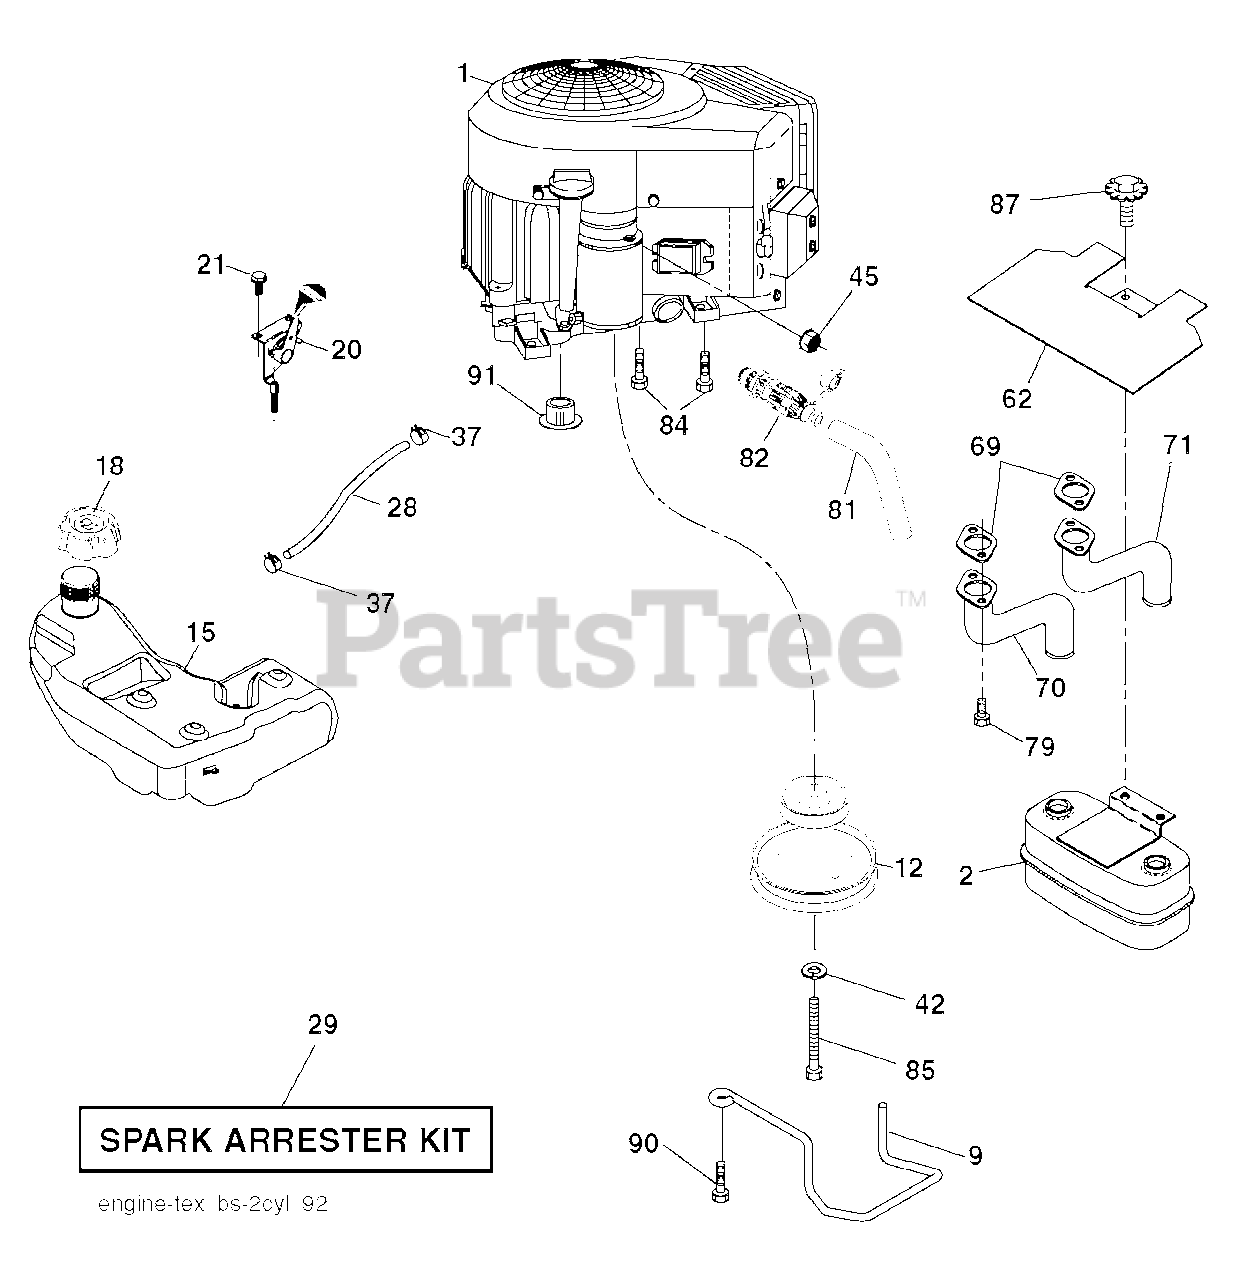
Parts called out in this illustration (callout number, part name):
2	MUFFLER.TWIN.CYL.LOW.TONE
9	KEEPER.BELT.ENGINE.4.2
12	PULLEY ENGINE
15	TANK.FUEL.4GAL
18	CAP.ASM.FUEL.TANK.3"BLACK
20	CONTROL.TH/CK.COBRA.B&S.TWN.
21	SCREW.#10 X 0.750.BOS THREAD
28	LINE.FUEL.20
29	ARRESTER SPARK (OPTIONAL)
37	HOSE CLAMP
42	LOCKWASHER
45	NUT
62	SHIELD.HEAT.MUFFLER
69	GASKET.MUFFLER
70	TUBE MANIFOLD LH
71	EXHAUST TUBE RH
79	SCREW.SOCKET.HEAD.5/16-18
81	TUBE, DRAIN OIL ASM.
82	VALUE.OIL.DRAIN
84	SCREW.3/8-16
85	BOLT HEX 7/16-20X4-1/4"
87	BOLT, 5/16-18 X 1 3/4
90	SCREW 3/8-16X1
91	BUSHING.1.375OD
